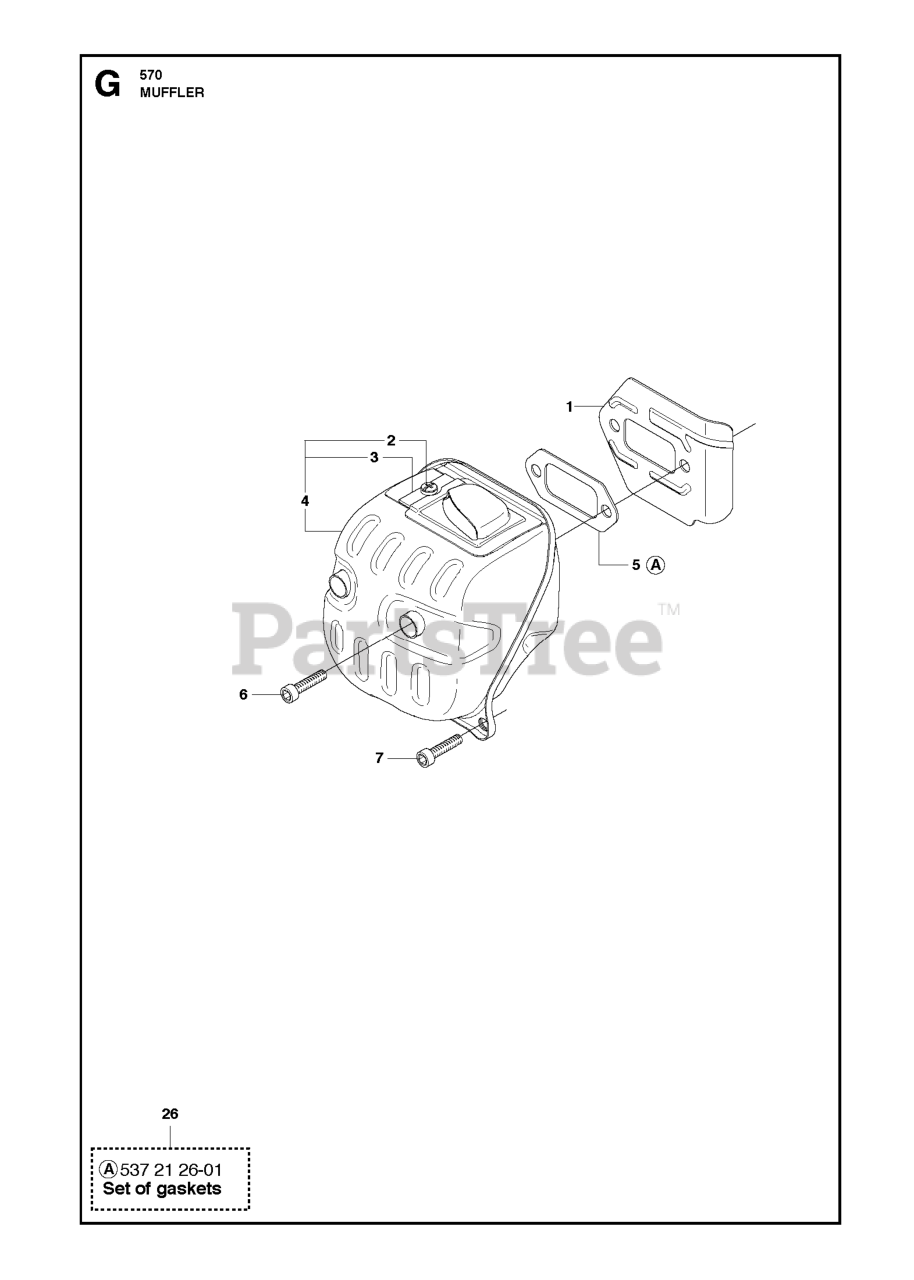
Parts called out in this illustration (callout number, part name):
4	MUFFLER ASSY (FF CE)
4	MUFFLER ASSY (DF US)
6	SCREW MC6S 6X20
26	GASKET SET
